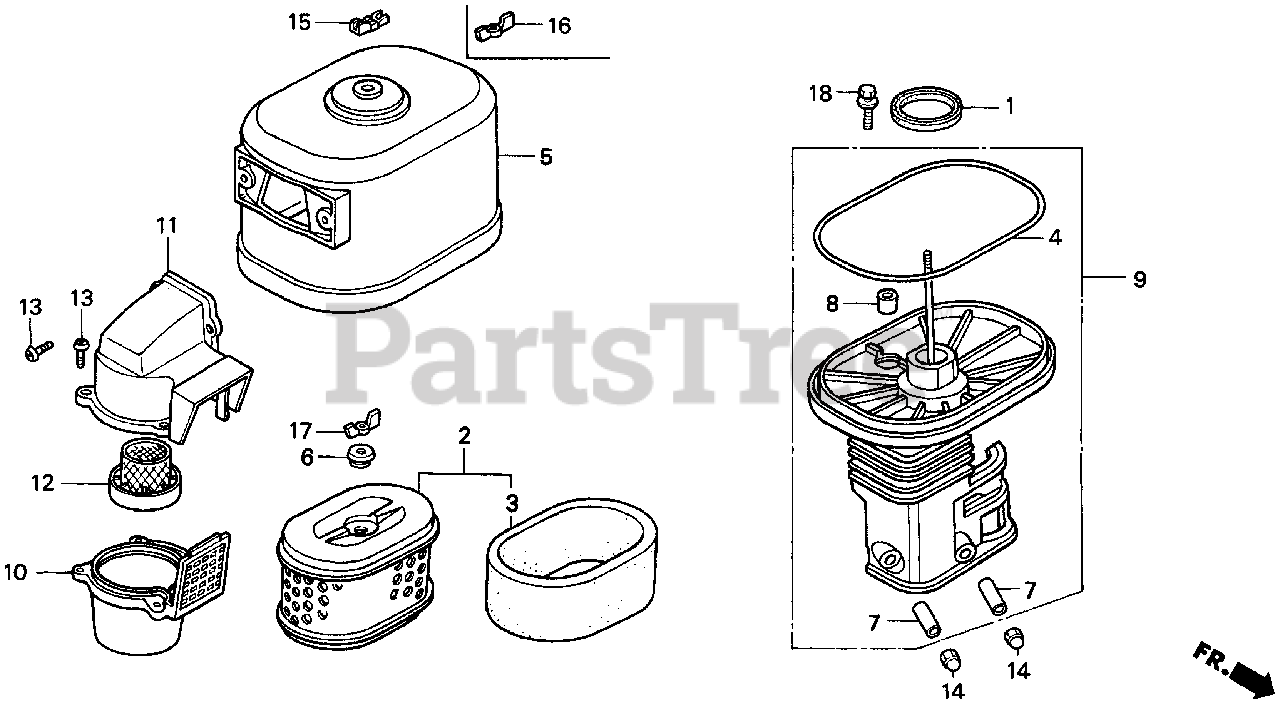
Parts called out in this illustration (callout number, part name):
1	GASKET, ELBOW
2	ELEMENT, AIR CLEANER
3	FILTER (OUTER)
4	SEAL, AIR CLEANER COVER
5	COVER, AIR CLEANER (CYCLONE)
6	GROMMET, AIR CLEANER
7	COLLAR, AIR CLEANER
8	COLLAR B, AIR CLEANER
9	ELBOW, AIR CLEANER
10	CASE, PRE AIR CLEANER
11	CAP, PRE AIR CLEANER
12	GUIDE, PRE AIR CLEANER
13	SCREW, PAN (5X16.5)
14	NUT, CAP (6MM)
14	NUT, FLANGE (6MM)
15	WINGNUT, AIR CLEANER COVER
15	WINGNUT (6MM)
16	WINGNUT, TOOL BOX SETTING
17	WINGNUT, TOOL BOX SETTING
18	BOLT-WASHER (6X22)
